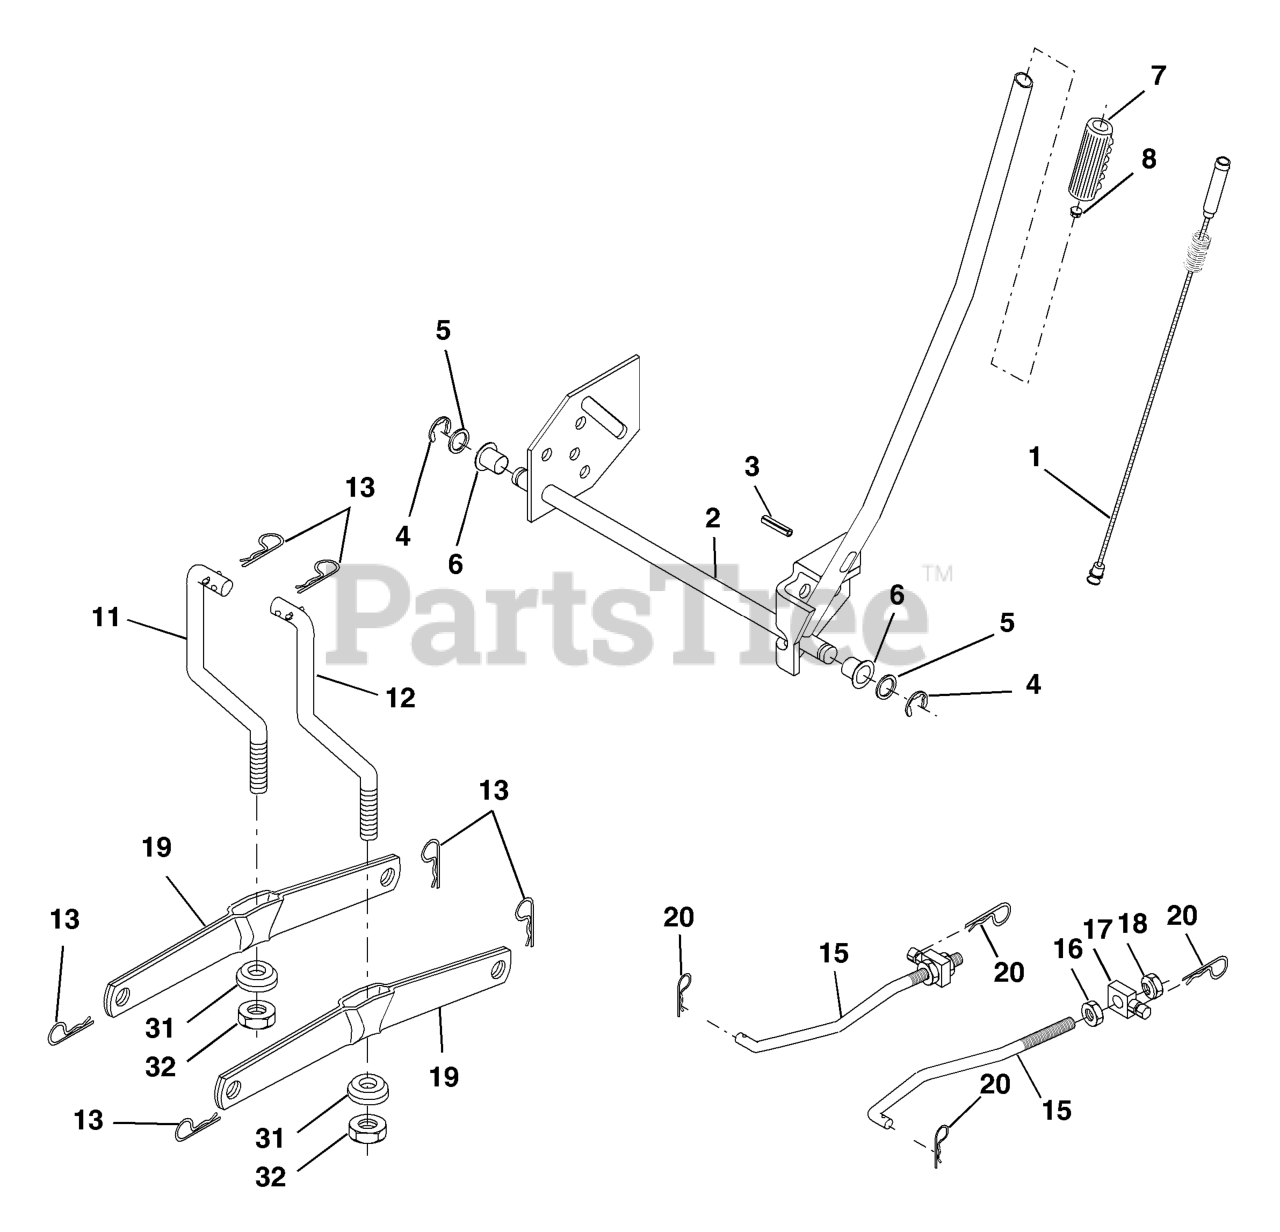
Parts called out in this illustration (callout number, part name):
1	WIRE ASM INNER W/ PLUNGER LT
2	SHAFT ASM R HANDLE
3	PIN GROOVE.
4	RETAINING RING LT
6	BEARING.NYLON
7	GRIP HANDLE
8	PLUNGER BUT KIT
11	LINK LIFT LH
12	LINK LIFT RH
13	RETAINER-SPRNG RB
15	LINK.SUSPENSION.FRONT
16	NUT.HEX.JAM.1/2-13
17	TRUNION
18	NUT.LK.W/WSH.1/2.
19	ARM.REAR.SUSPENSION
20	SPRING RETAINER
31	BEARING.PIVOT.LIFT
32	NUT CROWNLOCK 3/8-24
